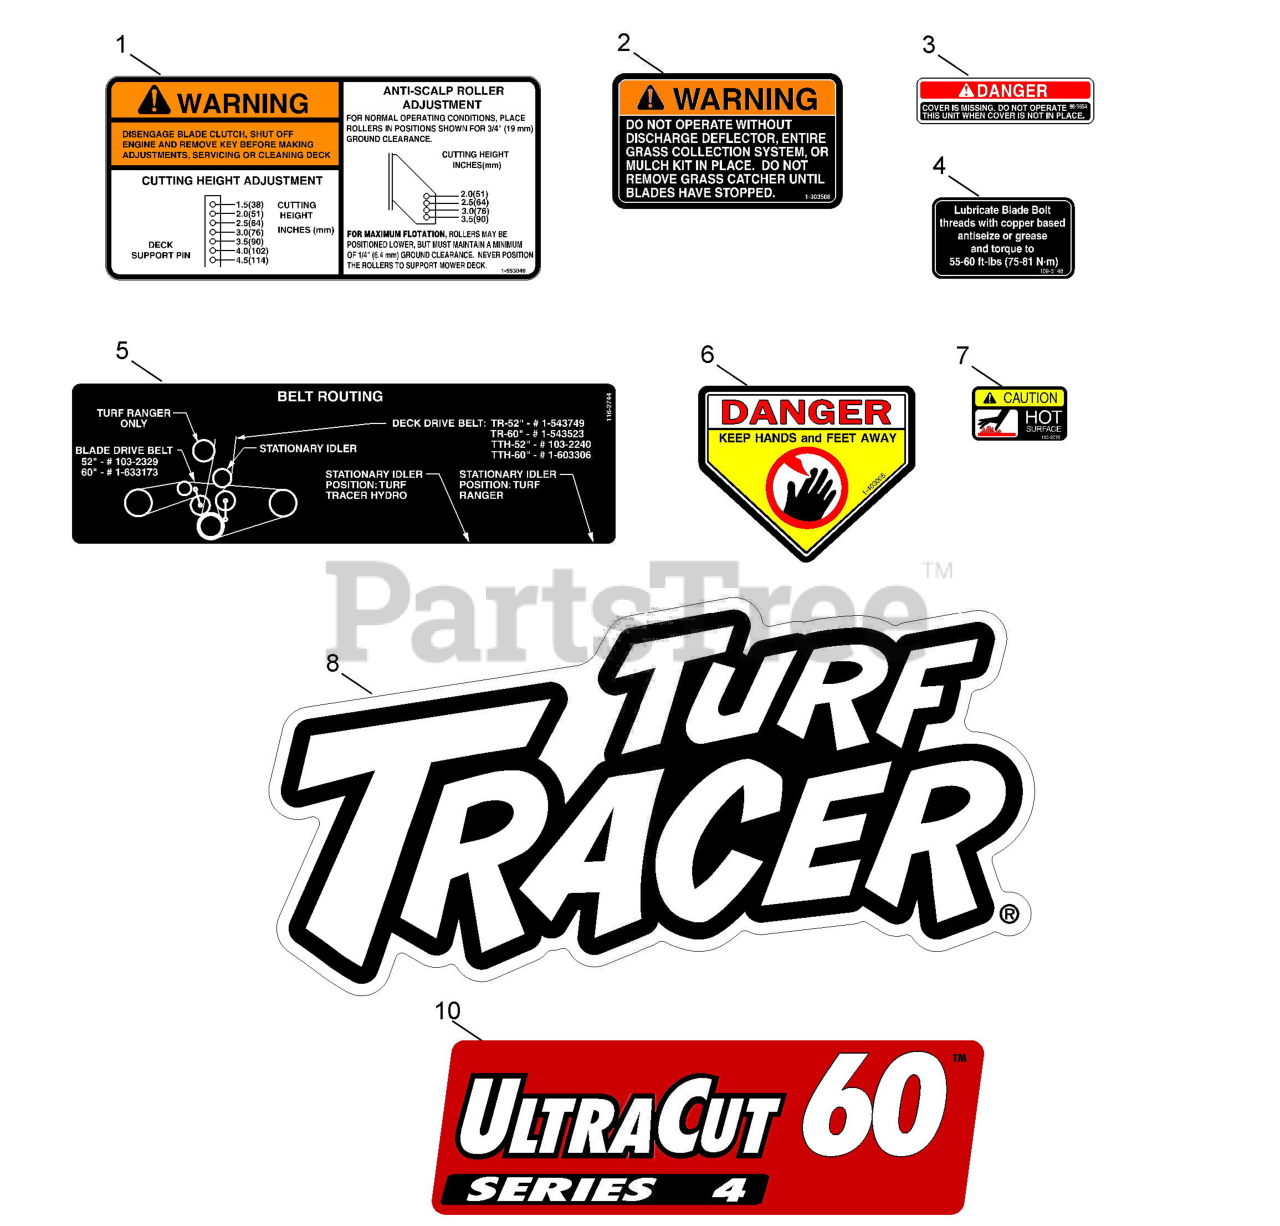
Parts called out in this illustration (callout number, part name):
1	DECAL,ANTI SCALP
2	DECAL-WARNING, DISCHARGE
3	DECAL-COVER, MISSING
4	DECAL,BOLT TORQUE
5	DECAL-BELT ROUTING
6	DECAL-DANGER
7	DECAL-CAUTION
8	DECAL,TTH MODEL
10	DECAL,ULTRACUT 60 SERIES
